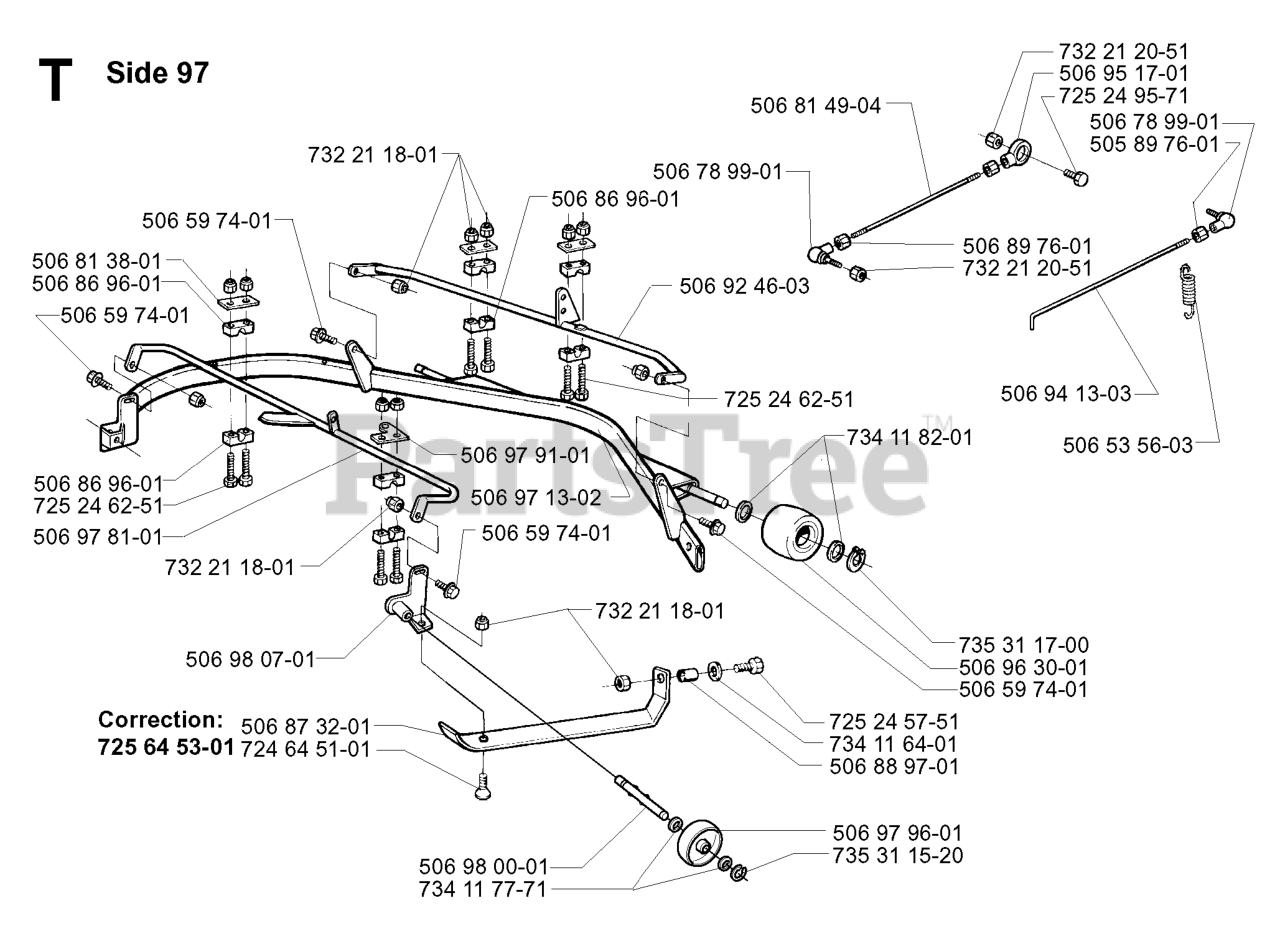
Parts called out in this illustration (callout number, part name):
1	SEAT
2	SEAT PIVOT BRKT
3	BOLT, HEX 3/8-16X1
6	NUT
7	SPRING COMPRESSION
8	SCREW 3/8-16X1
9	WASHER
10	PAN SEAT
12	BRKT SWITCH
14	BOLT.ROUND.HEAD.SQUARE.NECK
15	SPACER SPLIT 28X.96
17	NUT T
21	BOLT.SHOULDER.5/16-18
22	NUT.71038.31-18.HEX.NYLOCK
23	BOLT.HEX.BLACK
25	BOLT,SHOULD
26	LOCKWASHER
